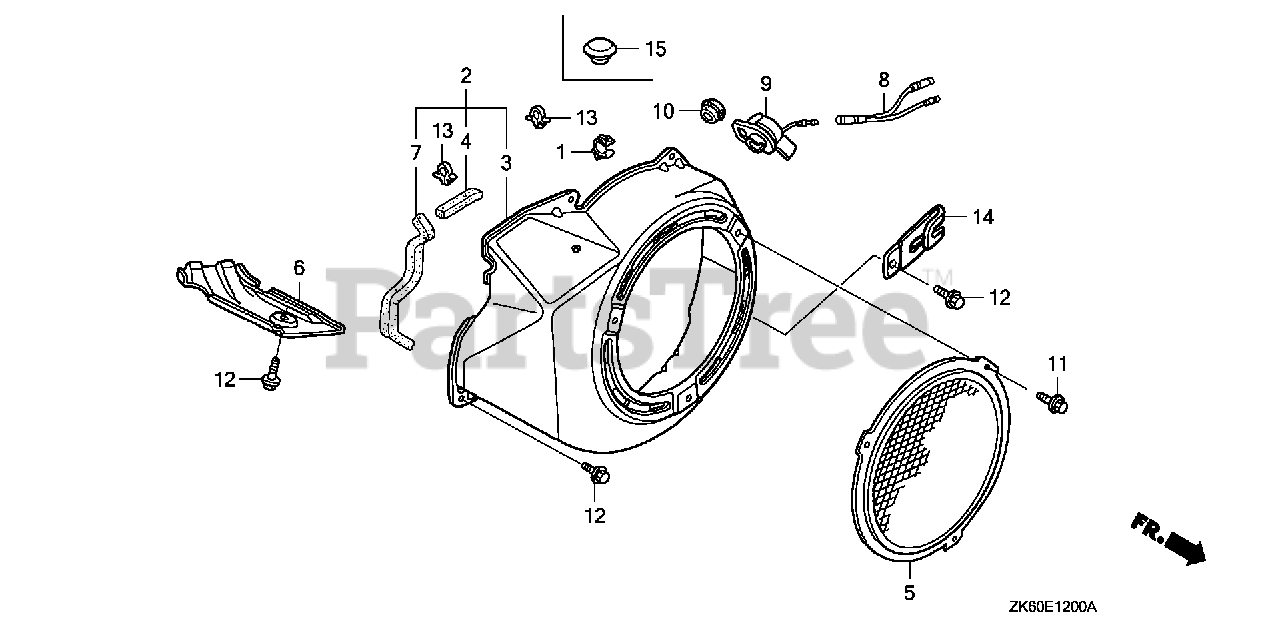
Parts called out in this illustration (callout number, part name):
1	CLIP, TUBE
3	COVER, FAN *R280* (POWER RED)
9	SWITCH ASSY., ENGINE STOP
12	BOLT, FLANGE (6X12) (CT200)
